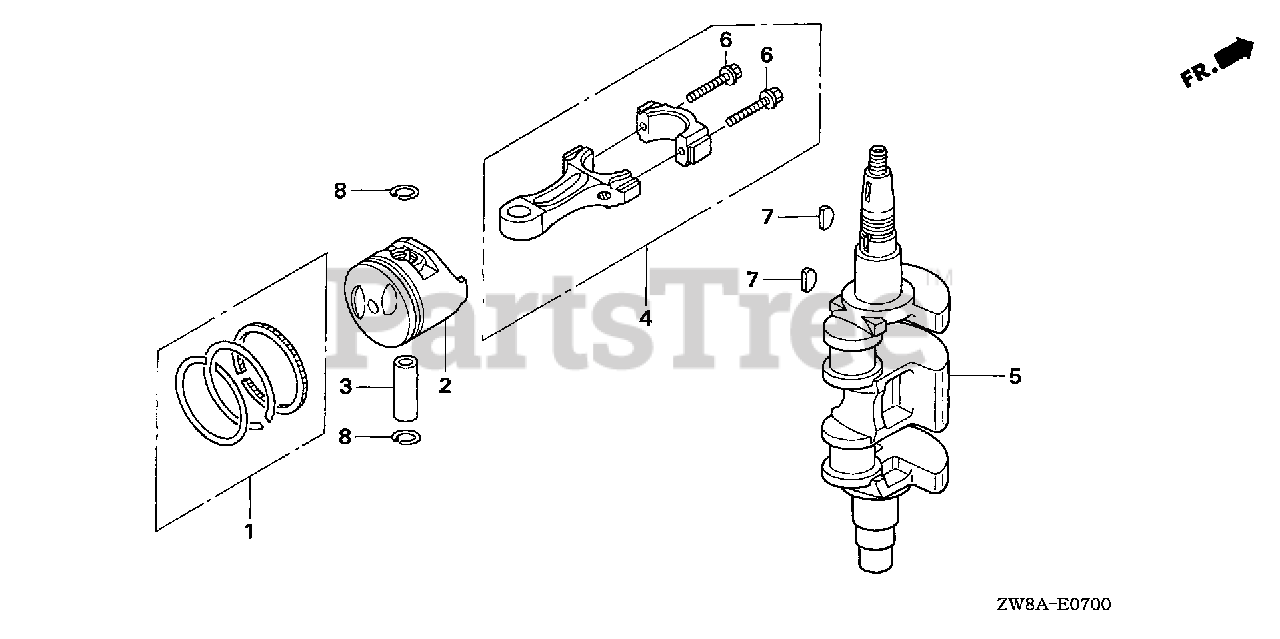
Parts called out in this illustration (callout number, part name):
1	RING SET, PISTON (STD)
3	PIN, PISTON
4	ROD, CONNECTING
5	CRANKSHAFT
6	BOLT, CONNECTING ROD (6X34)
7	KEY, SPECIAL (16X13)
8	CLIP, PISTON PIN (16MM)
